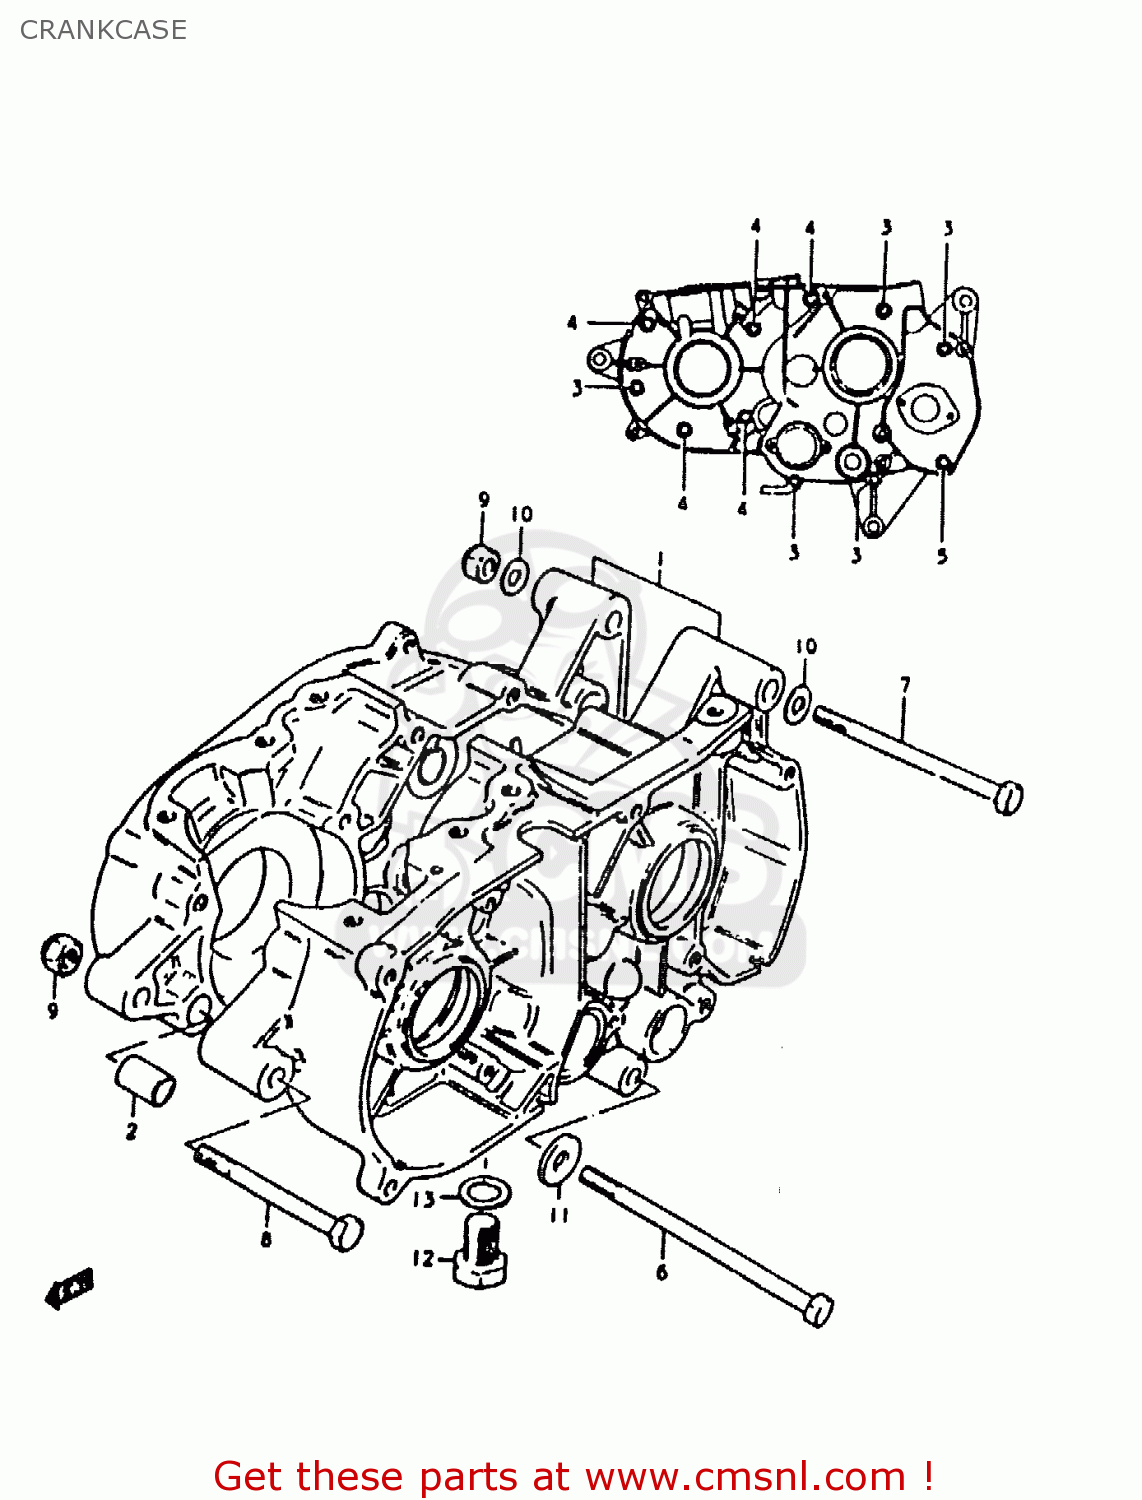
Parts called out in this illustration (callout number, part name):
1	CRANKCASE ASSEMBLY
2	PIN
3	SCREW (6X45)
4	SCREW (6X35)
5	SCREW
6	BOLT
7	BOLT
8	BOLT 8X75
9	NUT
10	WASHER
11	WASHER
12	BOLT 10X20
13	GASKET(10X14X3.6) (NAS)
